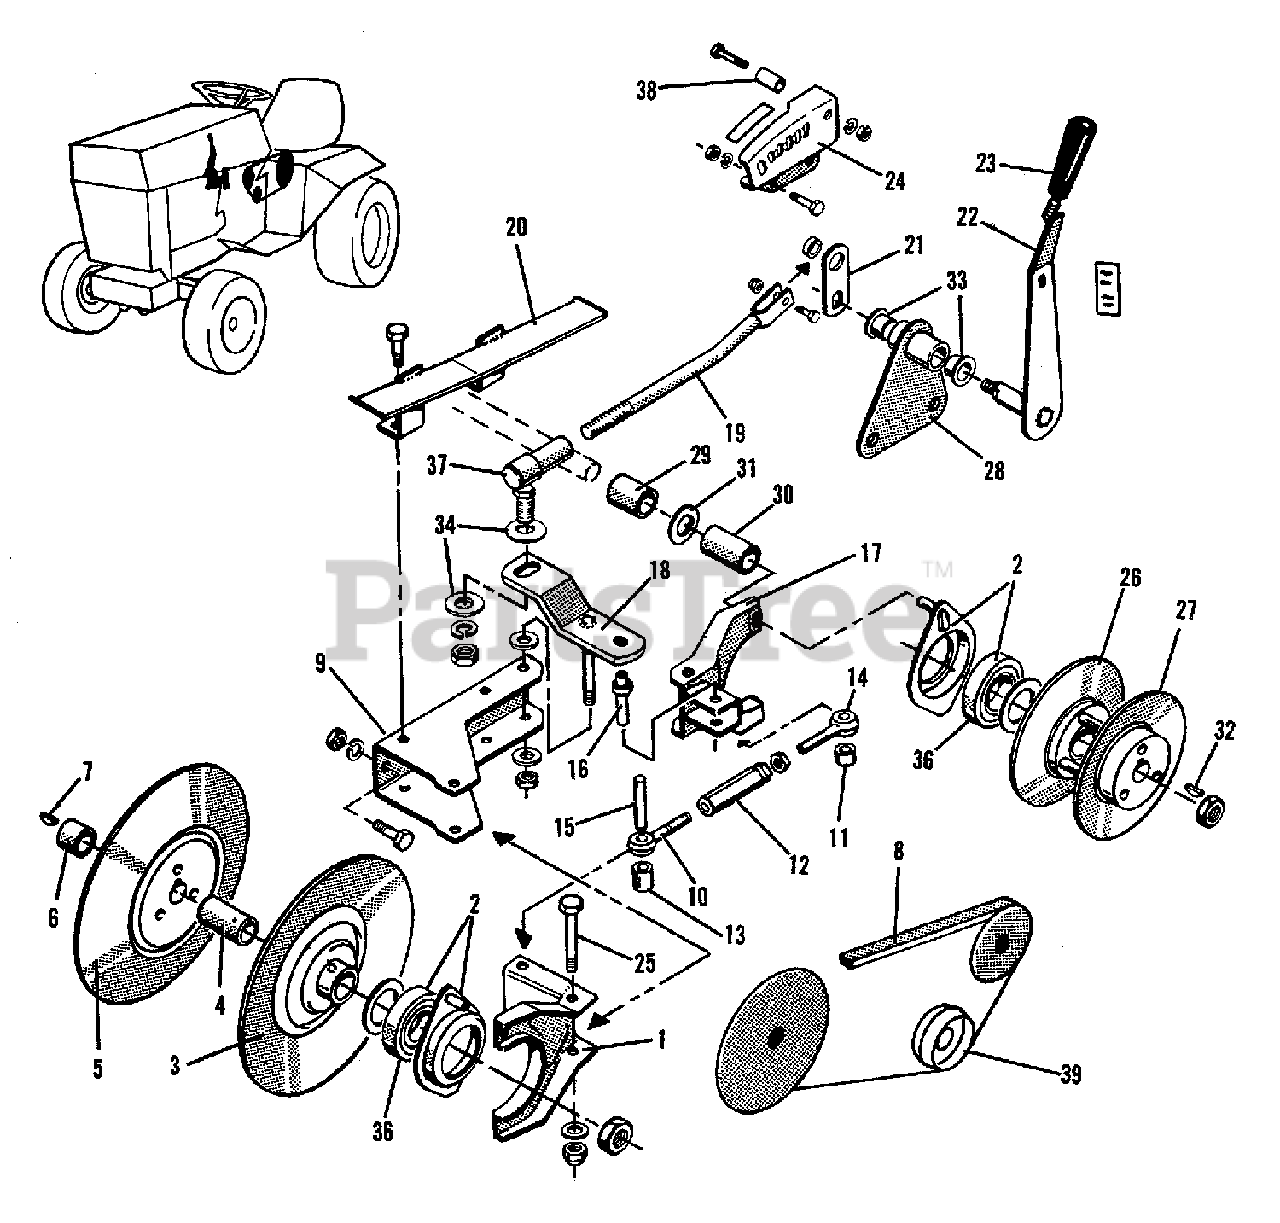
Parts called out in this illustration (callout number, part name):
1	FORK ASSEMBLY, Transmission
2	RETAINER ASSEMBLY, Bearing (Includes Items 35 & 36)
2	WASHER, 1-25/64 x 2 x 16 Ga.
3	PULLEY ASSEMBLY, Half
4	SPACER, Slide Driven
5	PULLEY ASSEMBLY, Half
6	SPACER, Slide Driven
7	KEY, Hi-Pro
8	BELT, HI, 54"
9	BRACKET, Variable Speed
9	CAPSCREW, 3/8NC x 7/8
9	LOCKWASHER, 3/8
9	NUT, 3/8NC
10	EYEBOLT, L.H.
10	NUT, 3/8NF
11	SPACER, Slide Driven
12	BODY, Turnbuckle
14	EYEBOLT, L.H.
15	PIN, Pivot
17	FORK ASSEMBLY, Bevel Gear Housing
18	ROCKER ASSEMBLY, Fork
18	NUT, Lock, 3/8 NC
19	LINK ASSEMBLY, Variable Speed
19	NUT, Jam, 1/2NF
20	GUARD ASSEMBLY, Belt
20	SCREW, Taptite, 1/4NC x 5/8
22	LEVER ASSEMBLY
22	WASHER, 3/8
22	LOCKWASHER, 3/8
22	NUT, 3/8NC
23	BALL, Control Lever
24	CAPSCREW, 1/4NC x 1/2
24	LOCKWASHER, 1/4
24	NUT, 1/4NC
25	SCREW, Special
25	WASHER, .083
25	NUT, Lock, 3/8 NC
26	PULLEY ASSEMBLY, Half
27	PULLEY ASSEMBLY, Half
27	NUT, Jam, 3/4NF
28	BRACKET ASSEMBLY, Support
29	SPACER (Prior S/N 15101001, 15201001, 15301001, 15401010, 15501031, 15601001, 15701001 & 15801077)
29	SPACER (Effective S/N 15101001, 15201001, 15301001, 15401010, 15501031, 15601001, 15701001 & 15801077)
30	SPACER (Prior S/N 15101001, 15201001, 15301001, 15401010, 15501031, 15601001, 15701001 & 15801077)
30	SPACER (Effective S/N 15101001, 15201001, 15301001, 15401010, 15501031, 15601001, 15701001 & 15801077)
31	WASHER, Stop
32	KEY, Hi-Pro
33	BUSHING, Flanged
34	WASHER, 1-25/64 x 2 x 16 Ga.
36	BEARING ASSEMBLY, Ball
37	JOINT ASSEMBLY, Ball
37	WASHER, 1/2
37	LOCKWASHER, 1/2
37	NUT, 1/2NF
38	CAPSCREW, 1/4NC x 1-1/2
38	LOCKWASHER, 1/4
38	NUT, 1/4NC
39	ILDER ASSEMBLY, (See BRAKE & CLUTCH For Components)
40	CAPSCREW, 3/8NC x 1
